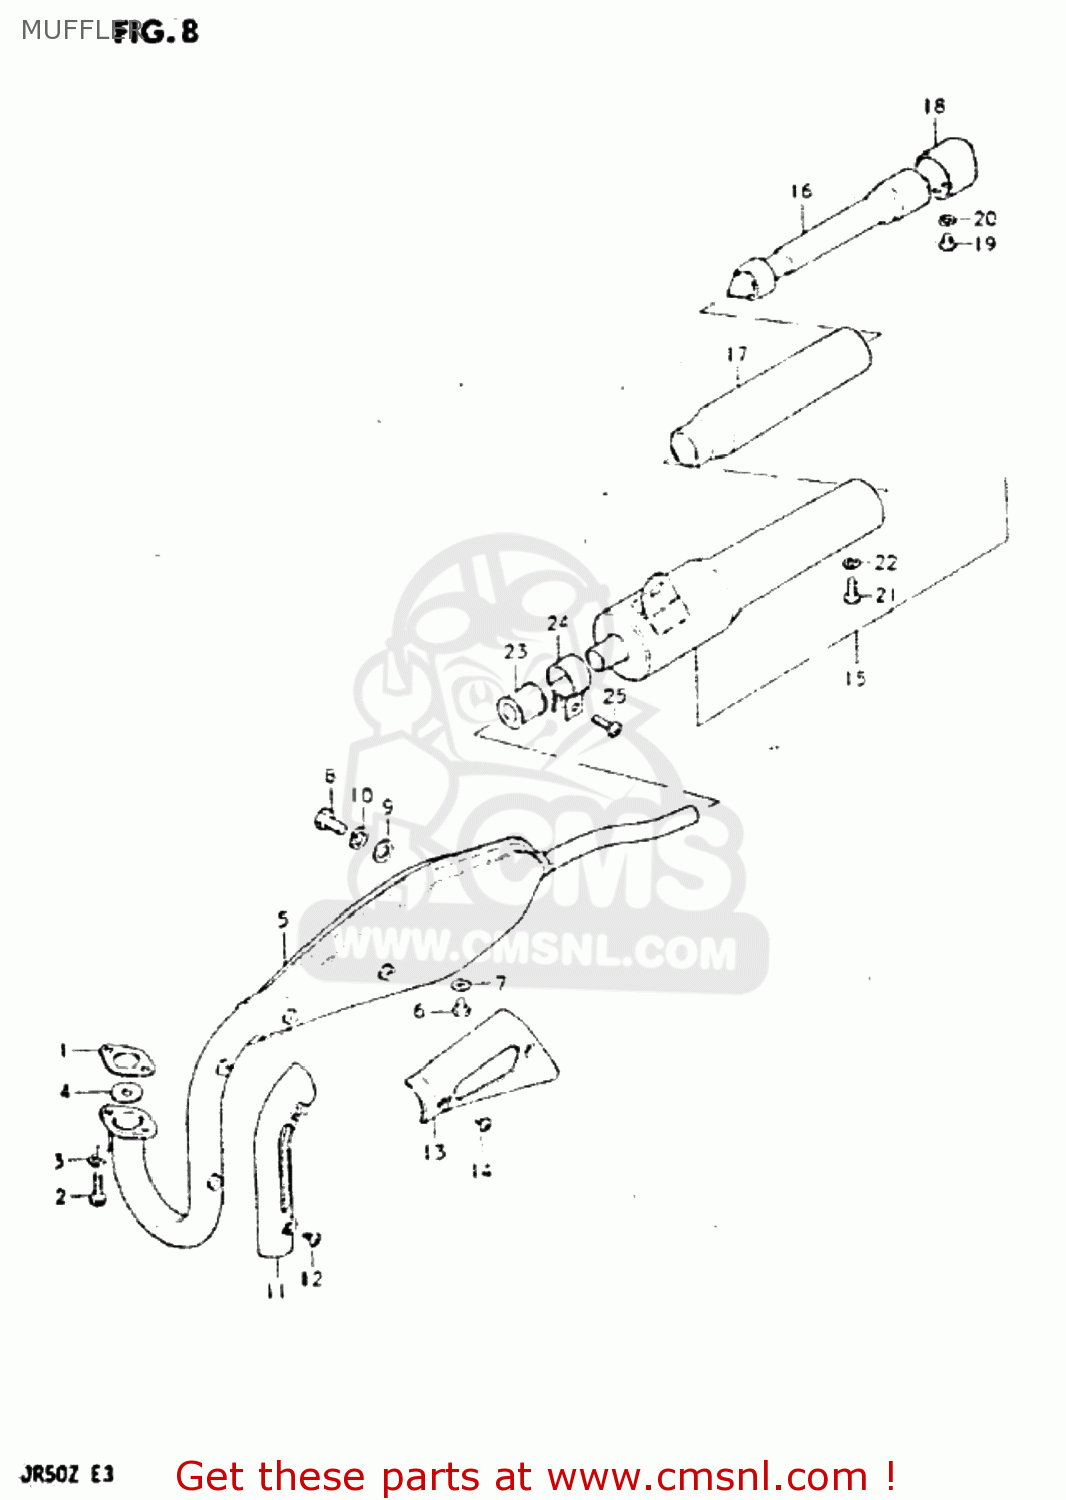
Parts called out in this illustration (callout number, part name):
1	GASKET,EXHAUST PIPE
2	BOLT
3	LOCK WASHER
4	PLATE,EXHAUST PIPE
5	MUFFLER ASSEMBLY
6	BOLT
7	WASHER
8	BOLT
9	WASHER (8.2X20X1.6)
10	LOCK WASHER
11	COVER,EXHAUST PIPE
12	SCREW
13	COVER,MUFFLER
14	SCREW
15	MUFFLER ASSEMBLY
16	TUBE,CLEAN OUT
17	SHELL,ARRESTER
18	CUTTER,MUFFLER TAIL
19	SCREW
20	LOCK WASHER
21	SCREW
22	LOCK WASHER
23	CONNECTOR,MUFFLER
24	CLAMP
25	SCREW
